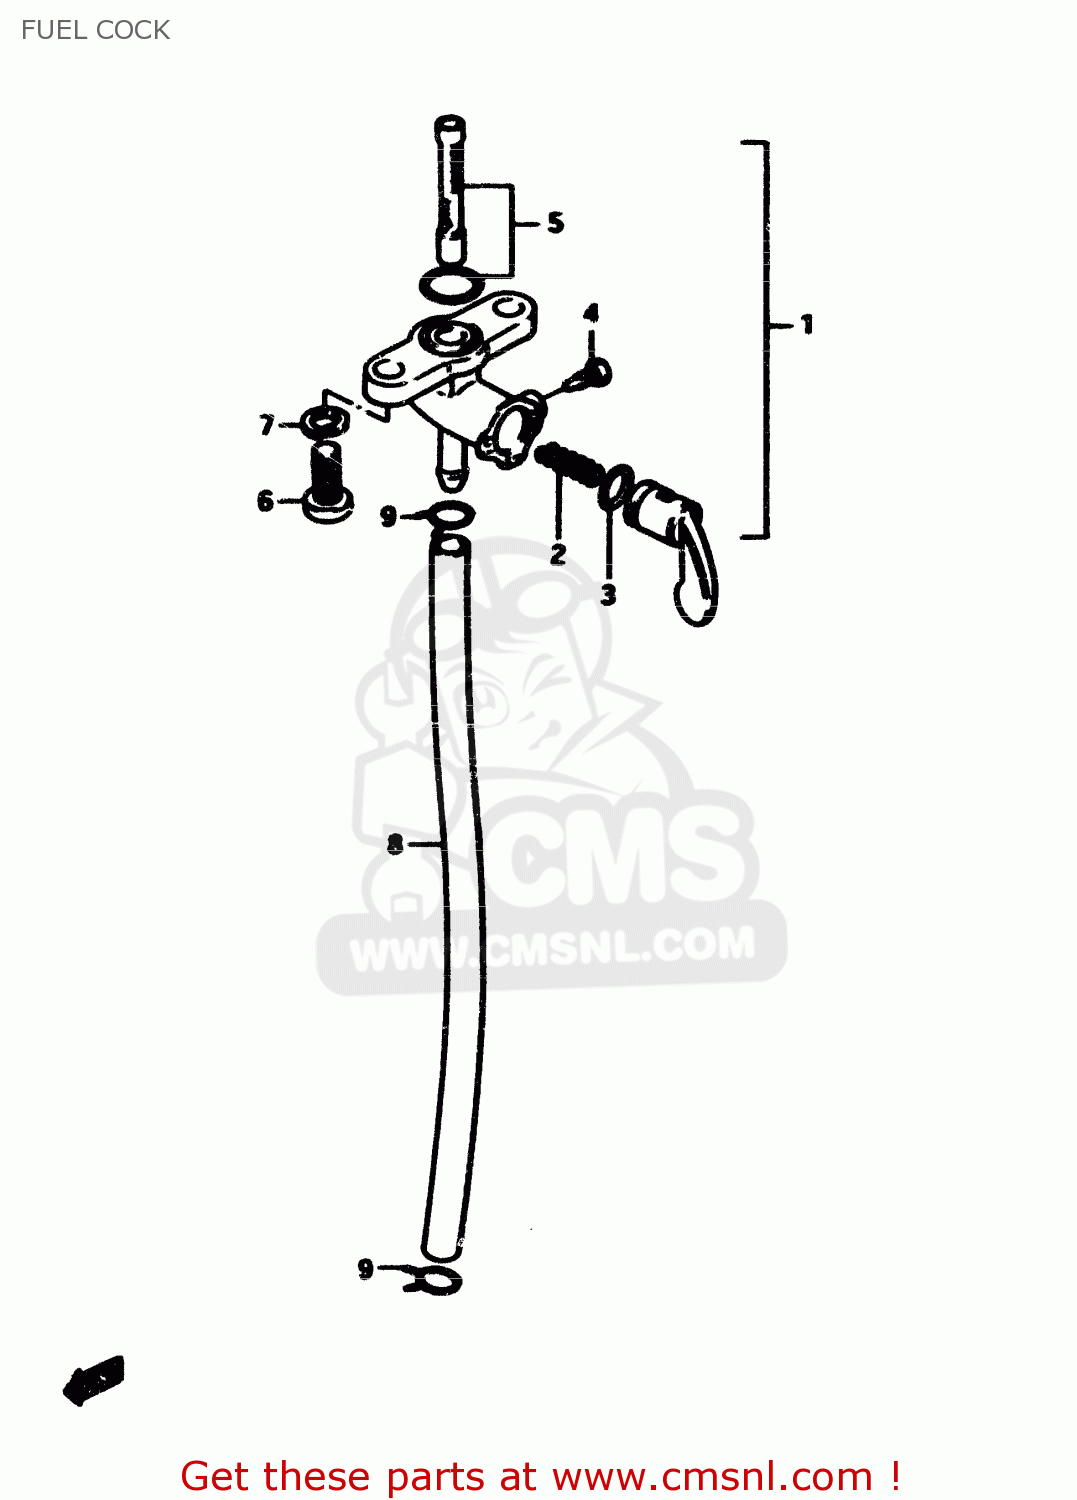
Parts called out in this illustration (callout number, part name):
1	COCK ASSY,FUEL
2	SPRING,FUEL COCK VALUE
3	O RING,LEVER
4	SCREW
5	FILTER SET FUEL
6	SCREW
7	LOCK WASHER
8	HOSE,FUEL
9	CLIP
